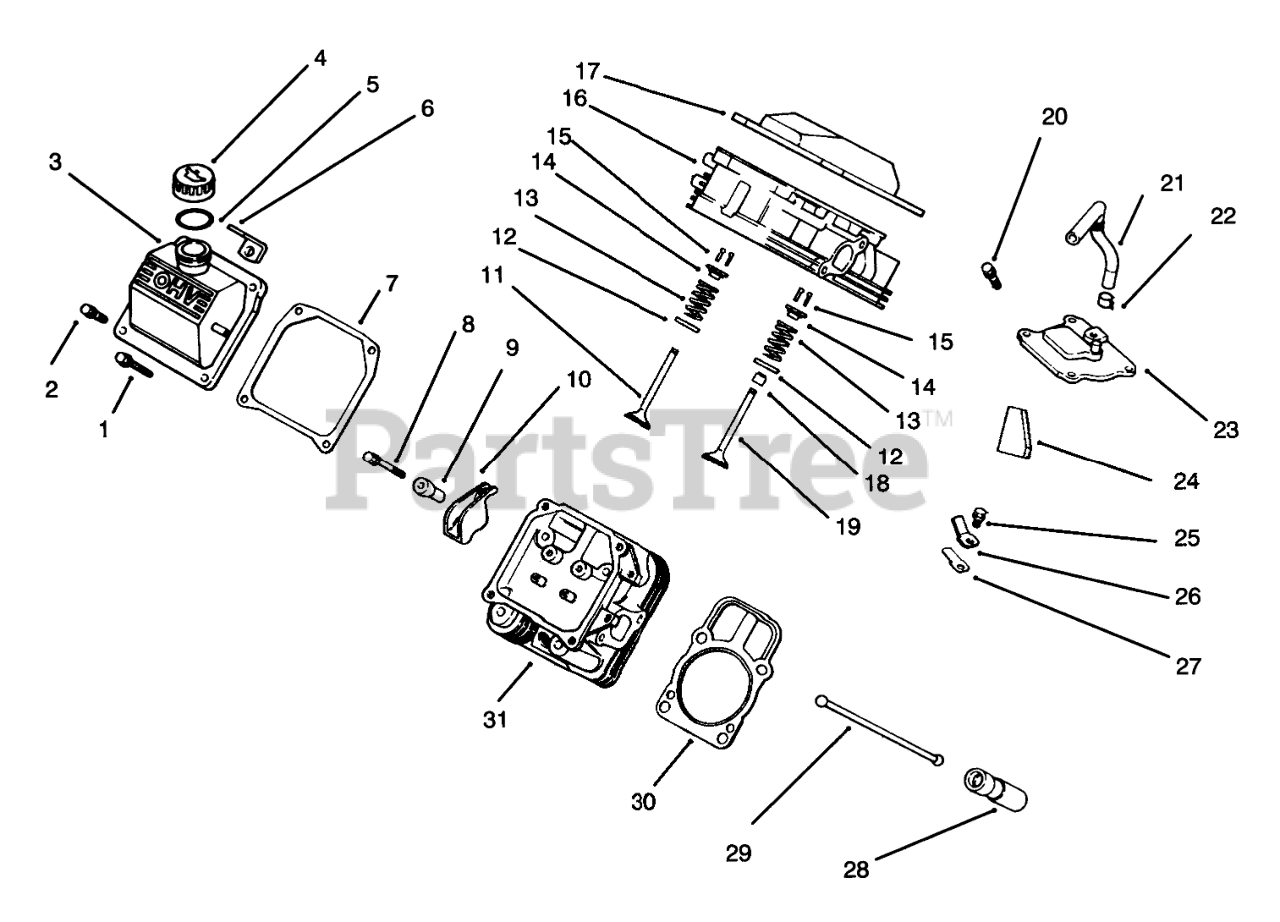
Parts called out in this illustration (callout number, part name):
1	Screw
2	Screw
3	Cove-Rocker
4	Cap-Oil Fill Tube
5	"O"Ring
6	Strap-Lifting
7	Gasket-Valve Cover
9	Ball-Rocker Pivot
10	Arm-Rocker
11	Valve-Exhaust
12	Retainer-Spring
13	Spring-Valve
14	Cap-Valve Spring
15	Kit-Retainer
16	Head Assembly #1 Cylinder
17	Cover-Rocker
18	Seal
19	Valve-Intake
20	Screw
21	Hose-Breather
22	Clamp
23	Kit,-Breather
24	Filter-Breather
26	Retainer-Reed
28	Lifter-Valve
29	Rod-Push
30	Gasket-Cylinder Head
31	Head Assembly #2 Cylinder
